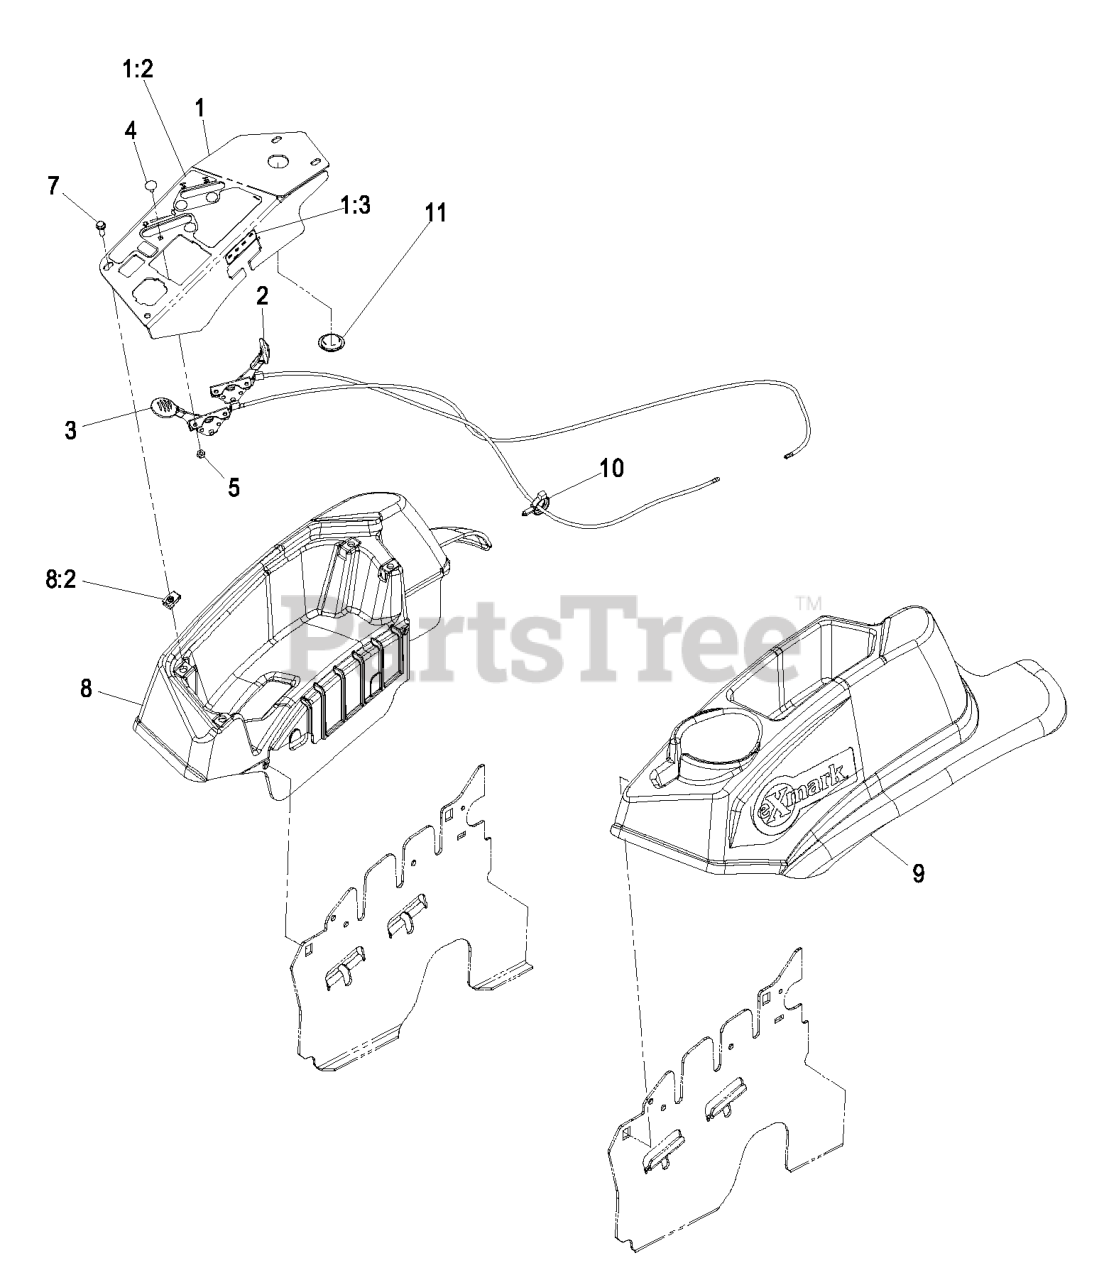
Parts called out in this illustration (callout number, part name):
1	CONSOLE,PANEL W/DECAL
1:2	DECAL-CONTROL PANEL
1:3	DECAL-FUSE
2	ASM, CHOKE CABLE
3	ASM,THROTTLE CABLE
4	BOLT-CARR
5	NUT-LOCK, NI
7	SCREW-HWH
8	CONSOLE,RH AS ASM
9	CONSOLE, LH AS
10	CLAMP-HOSE
11	PLUG-PLASTIC
